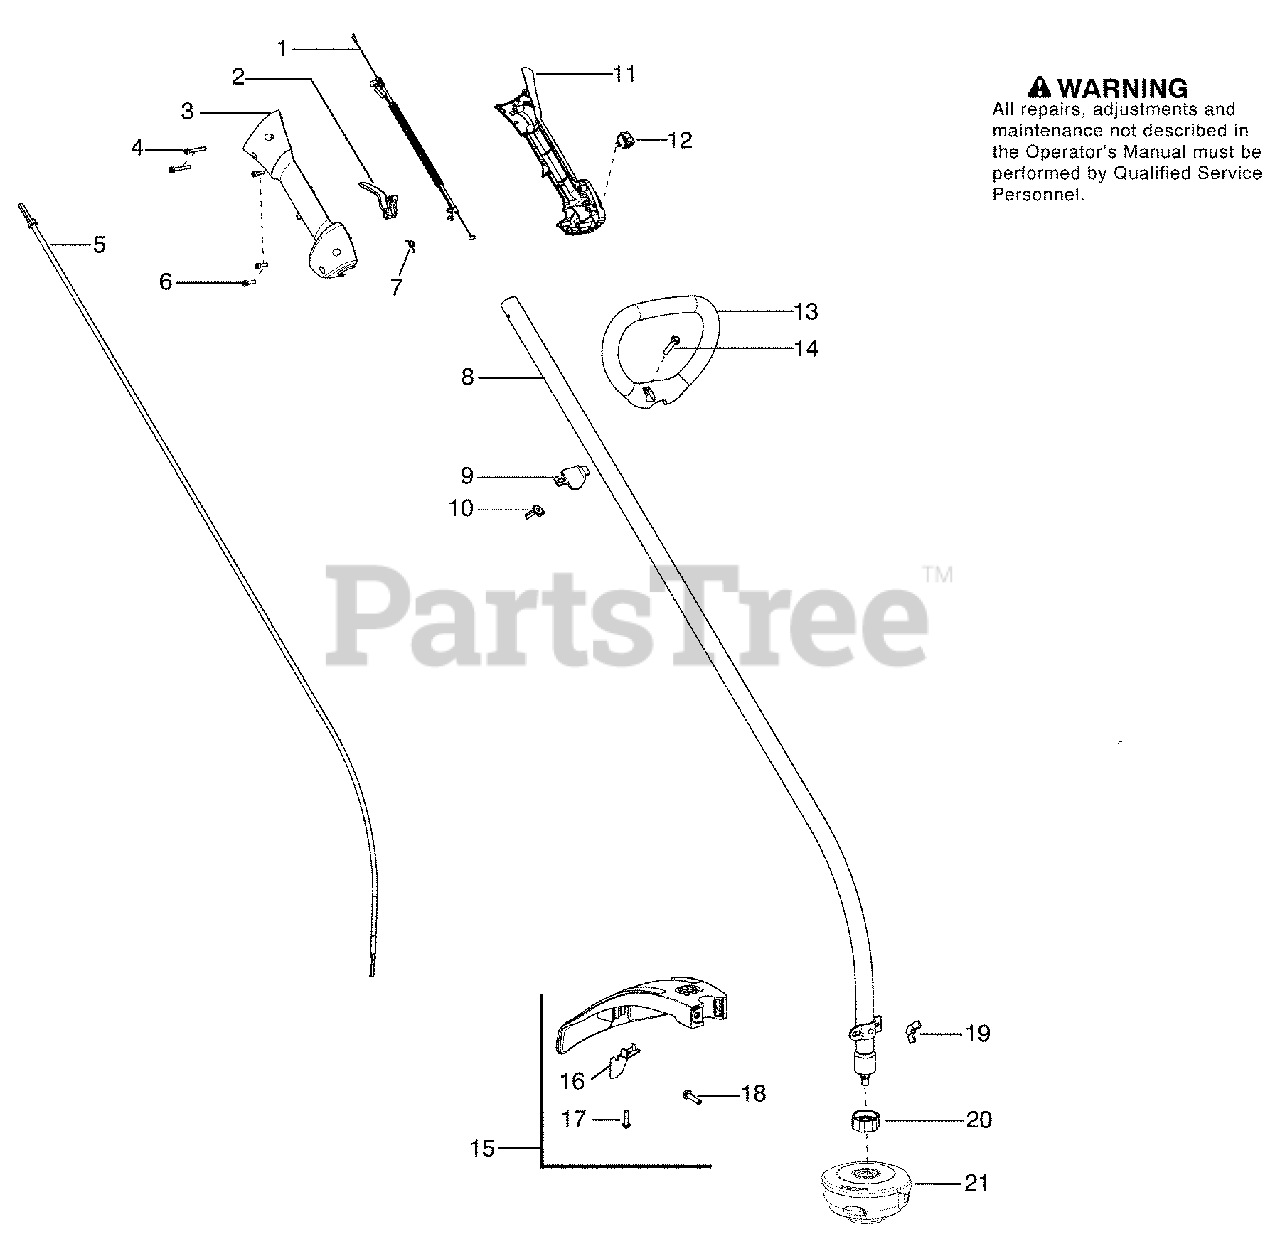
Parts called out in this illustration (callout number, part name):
1	Assy-Cable/Wire Harness
3	Housing-Throttle (RH)
5	Flexshaft
7	Spring-Trigger
8	Kit-Driveshaft
9	Clamp-Handle
10	Wingnut
11	Housing-Throttle (LH)
12	Kit-Switch
13	Handle-Assist
15	Kit-Shield
16	Kit - Limiter-Line
19	Wingnut
21	Assy-T25 Cutting Head
